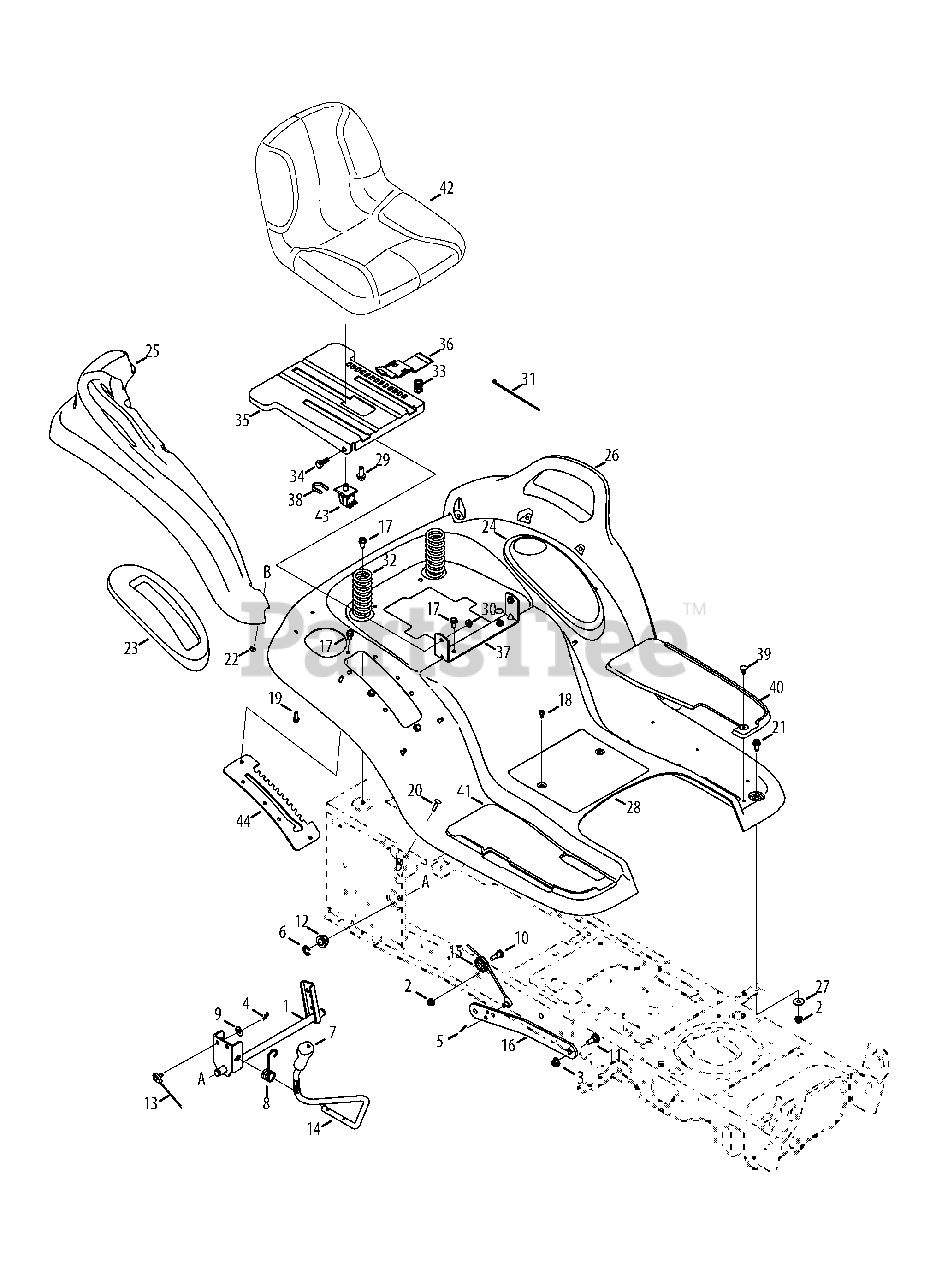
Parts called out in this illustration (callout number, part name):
1	Lift Shaft Assembly
2	Flangelock Nut, 5/16-18
3	Flangelock Nut, 3/8-16
4	Cotter Pin, .072 DIA. x 1.13 LG
5	Bow-Tie Cotter Pin
6	E-Ring, .625 DIA. SHAFT
7	Handle Grip
8	Torsion Spring
9	Spring Washer, .401 x .870 x .063
10	Shoulder Screw, .437 x .470:5/16-18
11	Shoulder Bolt, .500 x .270:3/8-16
12	Hex Flange Bearing
13	Lift Cable, 16.16 LG
14	Lift Handle
15	Pulley Roller Cable
17	Taptite Screw, Lock Washer, 5/16-18:.750
18	Taptite Screw, Lock Washer, 1/4-20
19	Hi-Lo Screw, Lock Washer, 1/4-15
20	Carriage Screw, 1/4-20:1.00
21	Taptite Screw, 5/16-18:.750
22	Sems Nut, 1/4-20
23	Lift Lever Cover
24	Cover with Cup Holder
25	RH Fender Flare
26	LH Fender Flare
27	Flat Washer, .344 x 1.00 x .063 HDN
29	Hex Head Flange, 3/8-16:.875
30	Flangelock Nut, 5/16-18
31	Cable Tie, 3/16 x .05 x 7.4
32	Compression Spring, 1.50 x 3.90 x .200
33	Compression Spring, .68 x 1.065 x .055
34	Shoulder Screw, .437 x .268:5/16-18
35	Seat Mounting Bracket
36	Seat Adjustment Lever
37	Seat Pivot Bracket
38	Switch Retainer Clip
39	Ratchet Clip
40	LH Foot Pad
41	RH Foot Pad
42	Seat
43	Seat Switch
44	Lift Bracket
